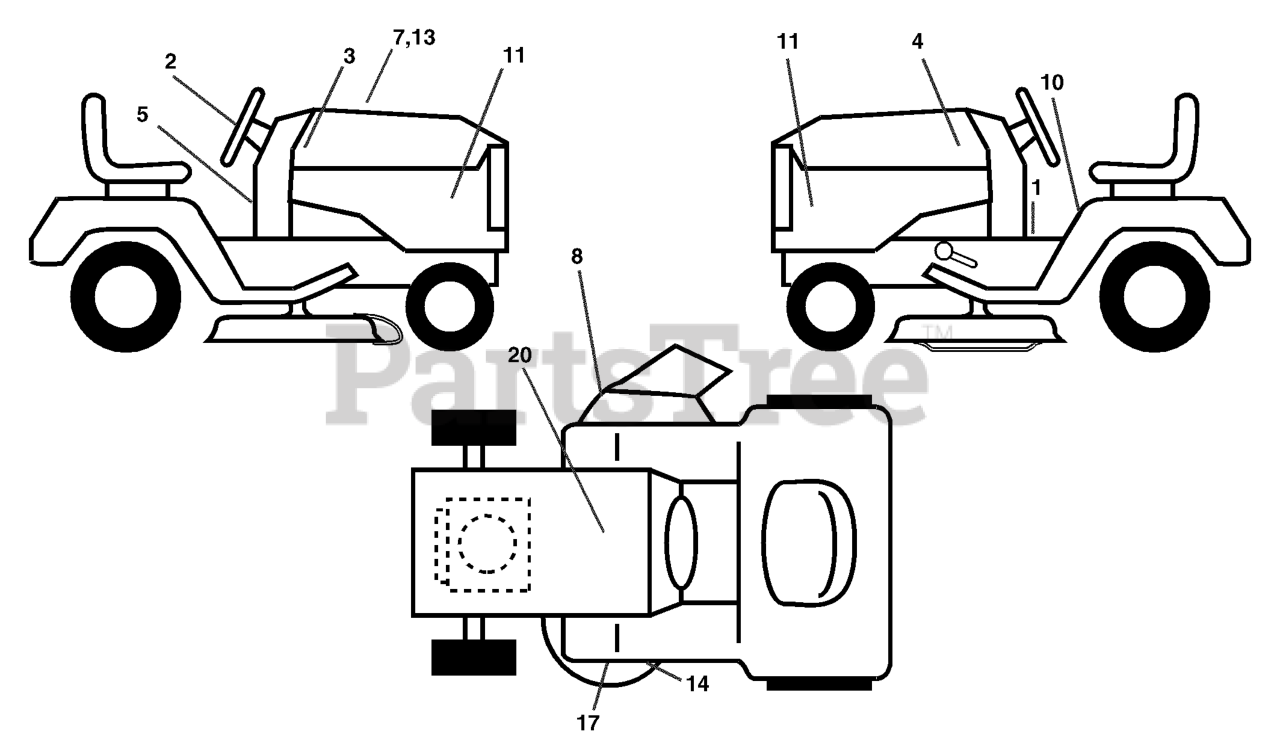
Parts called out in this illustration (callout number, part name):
2	DECAL.STEERING.HUSQ.BLUE
3	DECAL, HOOD RH
4	DECAL, HOOD LH
8	DECAL.WARN.KEEP.HAND.AWAY
10	DECAL FENDER DANGER
11	DECAL HOOD SIDES
13	DECAL HOOD CUST. RESP.
14	DECAL V-BELT SCHEMATIC
17	DECAL, MOWER HEAVY DUTY
20	DECAL BTRY SYMBOLS
